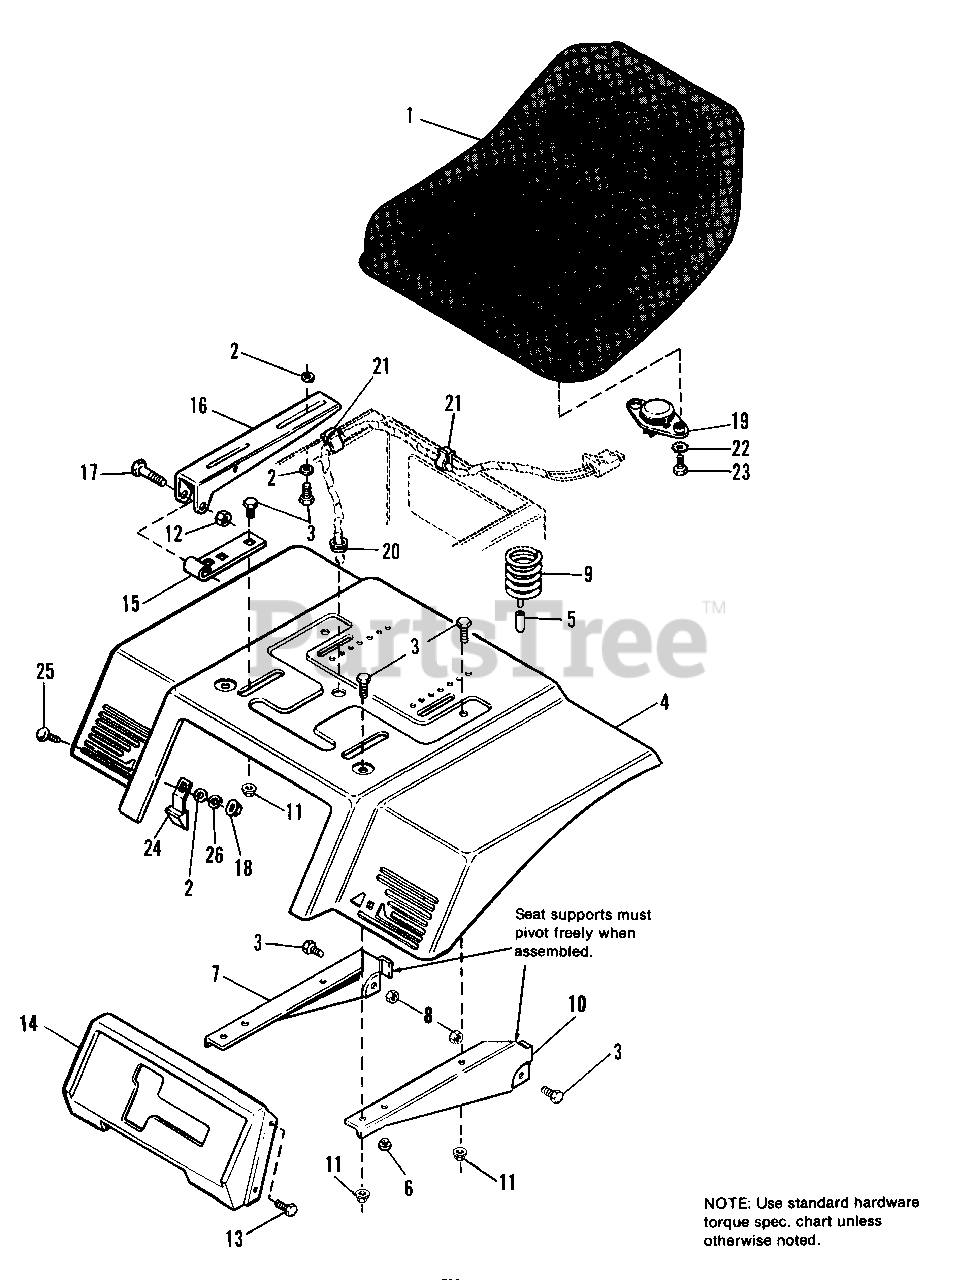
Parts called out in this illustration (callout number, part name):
2	WASHER, Plain, 5/16
3	CAPSCREW, Hex, 5/16-18 x 3/4
4	DECK Seat
5	COVER, Wire
6	BUMPER, Plug
7	SUPPORT, Seat, R.H.
8	LOCKNUT, Hex, 5/16-18
9	SPRING, Seat
10	SUPPORT, Seat, L.H.
11	NUT, Hex, Flange Whizlock, 5/17-18
12	LOCKNUT, Hex, 3/8-16
13	SCREW, Hex, Taptite, 5/16-18 x 3/8
14	PANEL, Shift
15	HINGE, Lower
16	HINGE, Upper
17	CAPSCREW, Hex, 3/8-16 x 2
18	NUT, Hex, Full, 5/16-18
19	SWITCH, Seat
20	BUSHING, Snap
22	LOCKWASHER, 1/4 Ext. Tooth
23	SCREW, Rd. Hd., 1/4-20 x 3/4
24	SEAT LATCH ASSY.
25	BOLT, Carriage, 5/16-18 x 3/4
26	LOCKWASHER, 5/16
